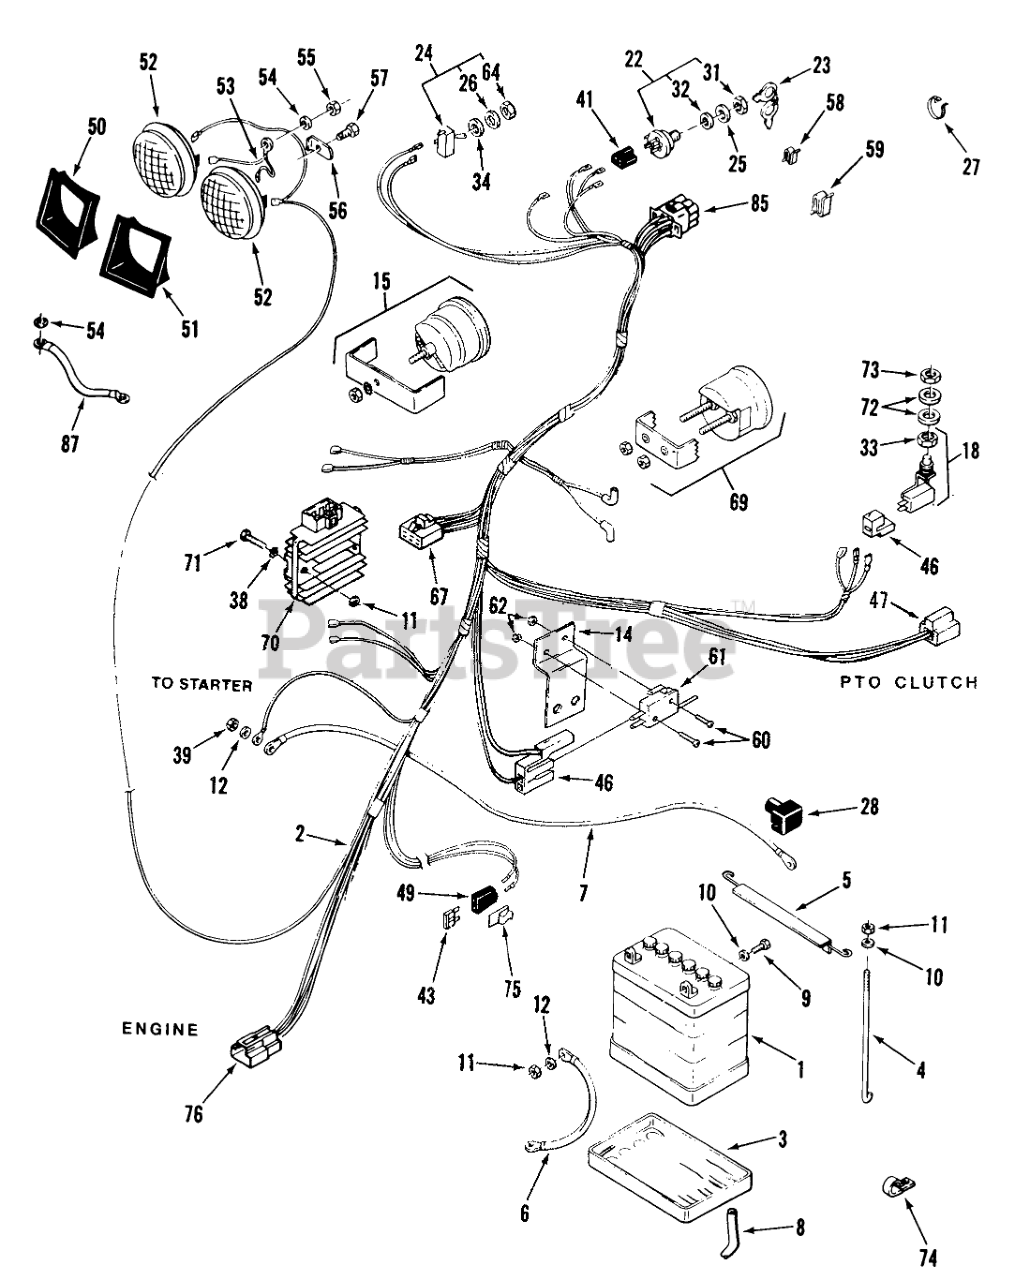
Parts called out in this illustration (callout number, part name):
1	Battery
2	MAIN-HARN & WIR DIA
3	TRAY-BATTERY
5	HOLDDOWN-BATTERY
6	WIRE - 14" BLACK
7	ASSY WIRE
8	TUBE-21" BATTERY DRAIN
9	Bolt
11	Nut
12	Washer
14	BRKT SWITCH BRAKE R
15	Hourmeter (Includes 114017 Gauge Mtg. Bracket, 915962 Keps Nuts (2)
18	Seat Switch
22	Ignition Switch (includes items 31 & 32)
23	Ignition Key
24	Light Switch (includes items 33 & 34)
25	Washer
26	Washer
27	PLASTIC TIE
28	Boot
32	LOCKWASHER
38	LOCKWASHER
39	Nut
41	CONNECTOR-5 WAY-SERV
43	FUSE-BLADE, 15 AMP
46	CONNECTOR BODY
47	CONNECTOR BODY
49	FUSE-BLOCK ASS'Y
50	BEZEL-HEADLIGHT, RH
51	BEZEL-HEADLIGHT, LH
52	HEADLAMP
53	LIGHT GROUND WIRE
54	Washer-Lock
55	Nut
56	LOCK-HEADLIGHT
57	Bolt
58	CLIP
59	SPEED CLIP
60	Screw
61	SWITCH - CLUTCH
62	NUT HEX 4-40 ELAST
67	CONNECTOR BODY
69	Voltmeter (Includes 109650 Clamp & 5924 = 10-32 Nut)
70	Voltage Regulator 257-H (Kawasaki #21066-2056)
71	HHCS 1/4-20X1" WHIZ
72	Washer
73	NUT-HEX SPECIAL
74	CLAMP
75	MOUNTING-CLIP CONN
76	3-CONTACT LOCK-TYPE
85	9-Terminal Connector
87	WIRE-LIGHT GROUND
